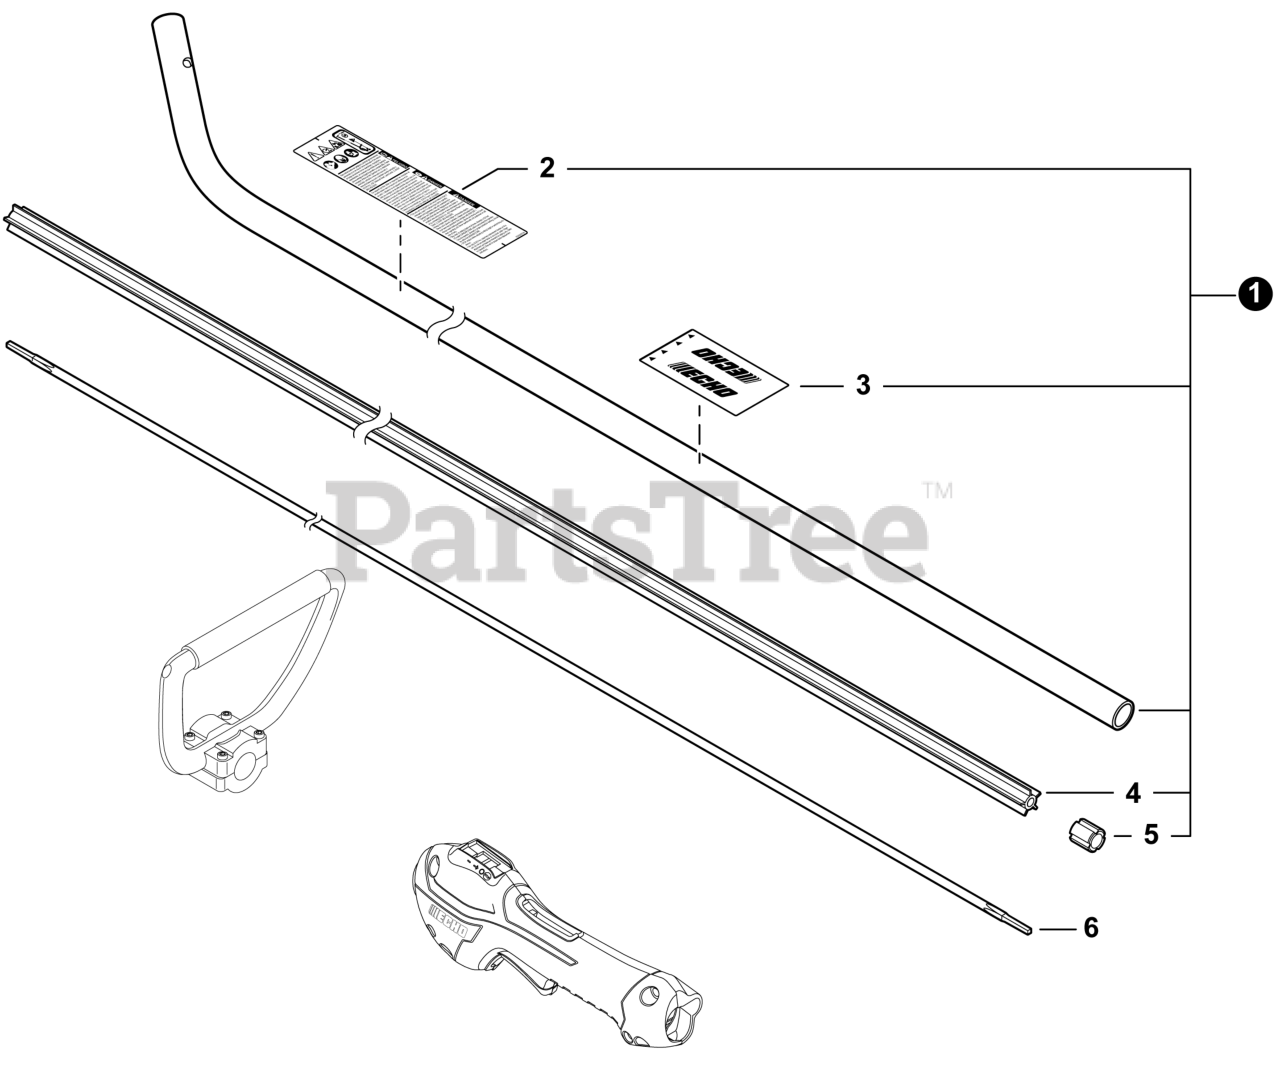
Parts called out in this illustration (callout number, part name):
1	MAIN PIPE ASSY
2	LABEL - CAUTION
3	LABEL - HANDLE LOCATION
4	LINER, FLEXIBLE 21.6x1420
6	DRIVESHAFT - FLEXIBLE
